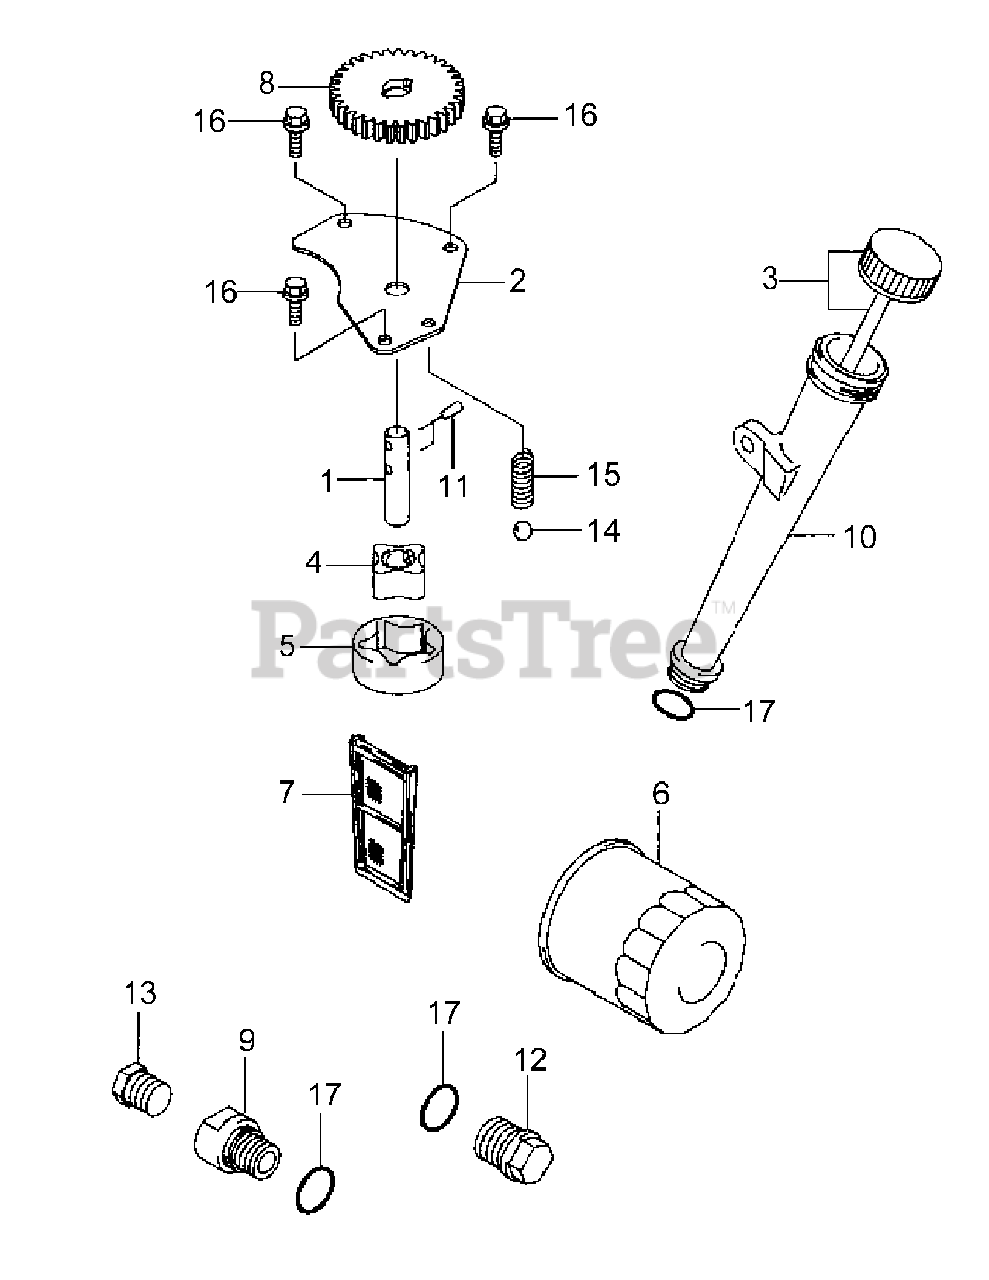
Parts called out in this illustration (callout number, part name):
1	SHAFT
4	ROTOR-PUMP, IN
5	ROTOR-PUMP, OUT
6	FILTER-OIL
9	JOINT
11	PIN
12	PLUG
13	PLUG
16	BOLT-FLANGED
17	O RING, 16MM
